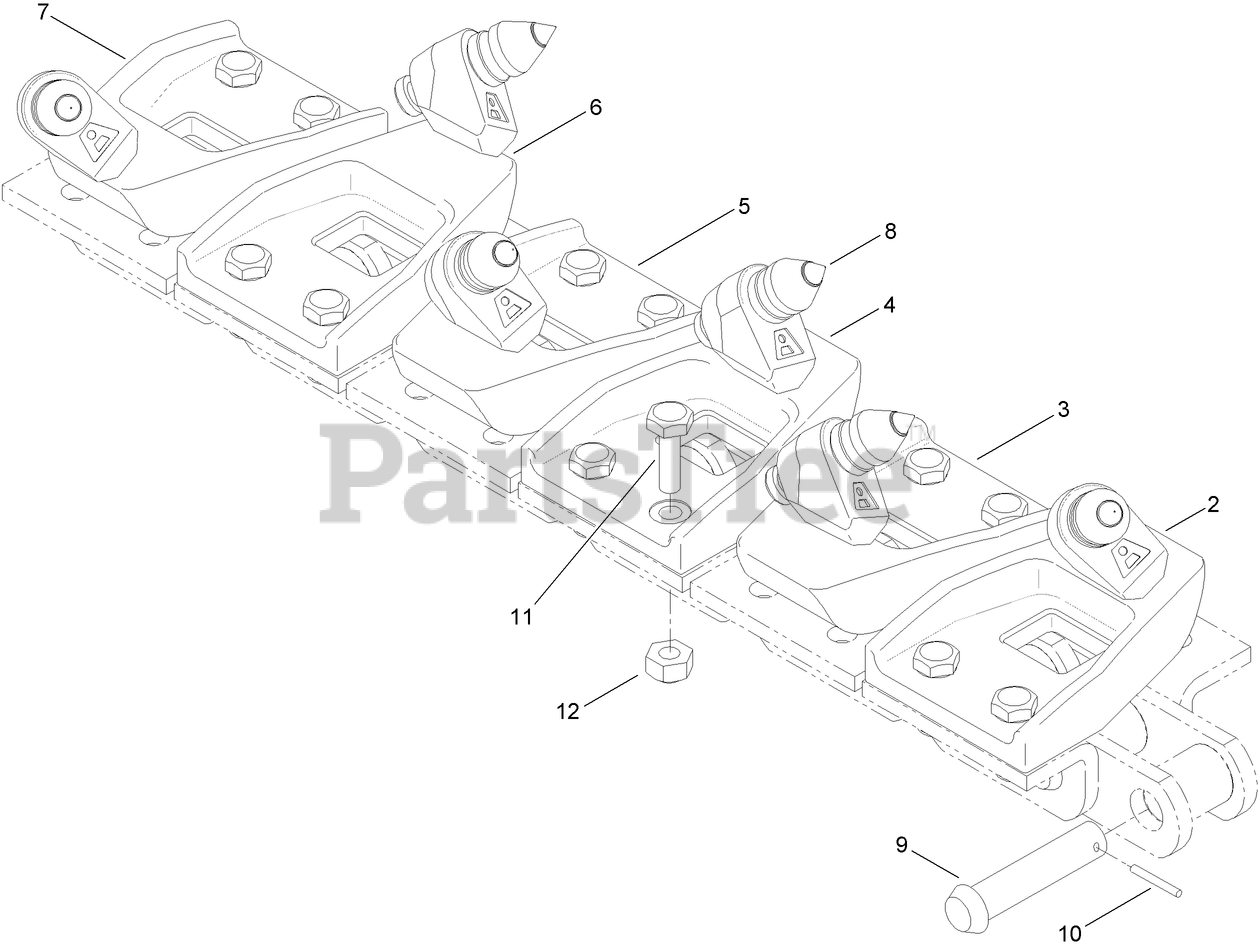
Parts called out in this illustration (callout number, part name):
2	TOOTH-ROCK (1" L)
3	TOOTH-ROCK (1" R)
4	TOOTH-ROCK (3" L)
5	TOOTH-ROCK (3" R)
6	TOOTH-ROCK (6" L)
7	TOOTH-ROCK (6" R)
8	BIT-CONICAL
9	PIN-MASTER
10	PIN-KEEPER, MASTER
12	NUT-LOCK
